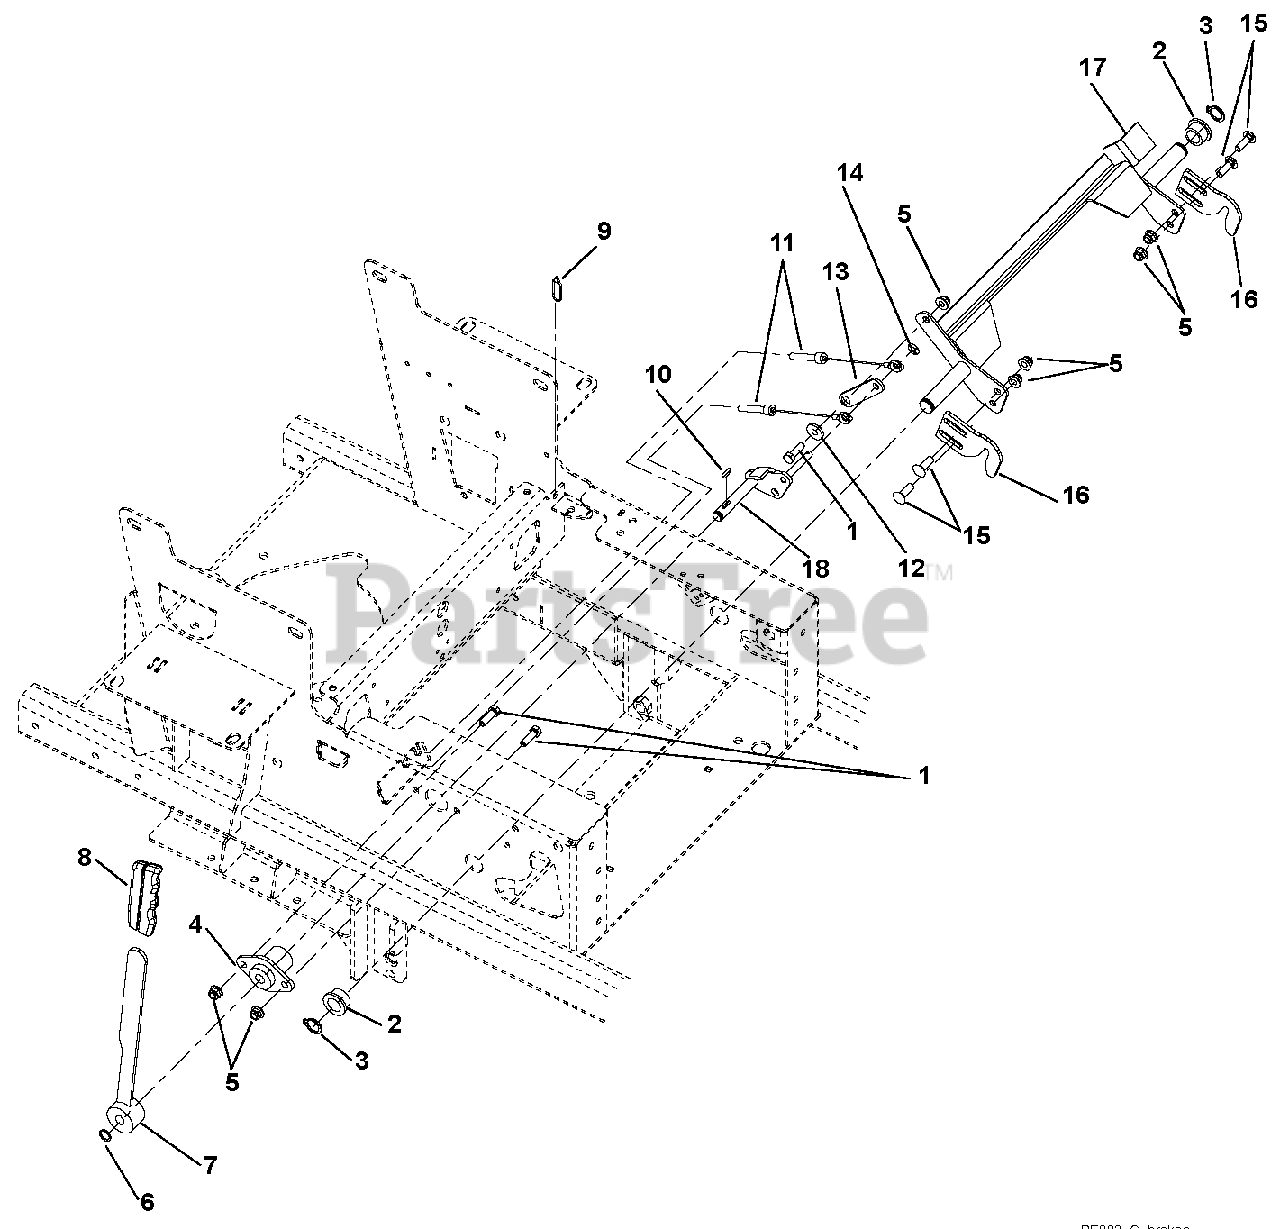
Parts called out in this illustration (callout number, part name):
1	Bolt, Hex .31-18 x 1.00
2	Bushing, Flange .750 x 1.000 x .625 x 1.250
3	Ring, Retaining External .689 x .077
4	Bushing, Flanged
5	Nut, .31-18 Nyloc Flange
6	Ring, Retaining External .500 x .050
7	Weldment, Parking Brake Arm
8	Grip, Parking Brake
9	Cable Tie
10	Key, Woodruff .13 x .63 HRD #5
11	Cable, Brake Actuating
12	Bushing, Flange .325 x .499 x .26 x .88
13	Plate, Neutral Interlock
14	Nut, Push .312
15	Bolt, Round Head Square Neck .31-18 x 1.00
16	Neutral Lock Latch
17	Weldment, 100I Neutral Lock
18	Weldment, Park Brake Arm
